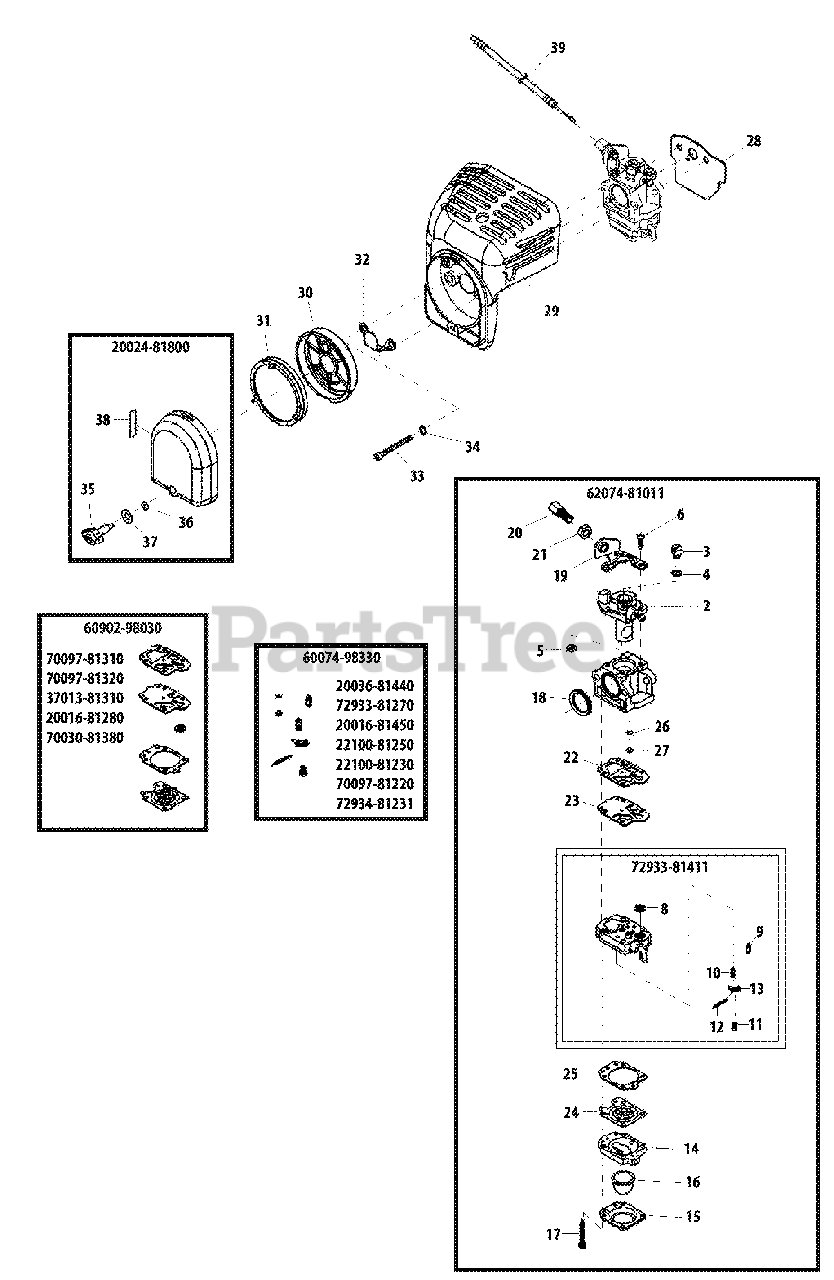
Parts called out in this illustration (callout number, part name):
2	THROTTLE VALVE SET
3	SWIVEL
4	WASHER
5	E-RING
6	SCREW
8	SCREEN, FUEL INLET
9	VALVE, INLET NEEDLE
10	SPRING, METERING LEVER
11	SCREW
12	PIN, METERING LEVER
13	LEVER, METERING
14	BODY ASSY, PURGE
15	RETAINER, PURGE BULB
16	BULB, PURGE
17	SCREW
18	RING, PACKING
19	BRACKET, THROTTLE CABLE
20	ADJUSTER, THROTTLE CABLE
21	NUT, ADJUSTER LOCK M7
22	GASKET, PUMP
23	DIAPHRAGM, PUMP
24	DIAPHRAGM, METERING
25	GASKET, METERING DIAPHRAGM
26	O-RING
27	JET, MAIN #37
28	GASKET
29	AIR FILTER CASE ASSY
30	SCREEN, REAR AIR FILTER
31	FILTER, HEAVY-DUTY AIR
32	PLATE
33	BOLT M5×55
34	WASHER, SPRING 5
35	THUMBSCREW
36	O-RING
37	WASHER, CONE M6
38	LABEL, CHOKE
39	CABLE, THROTTLE
2002481800	AIR FILTER COVER ASSY
6007498330	REPAIR KIT
6090298030	GASKET / DIAPHRAGM KIT
6207481011	CARBURETOR
7293381411	BODY ASSY, PUMP
